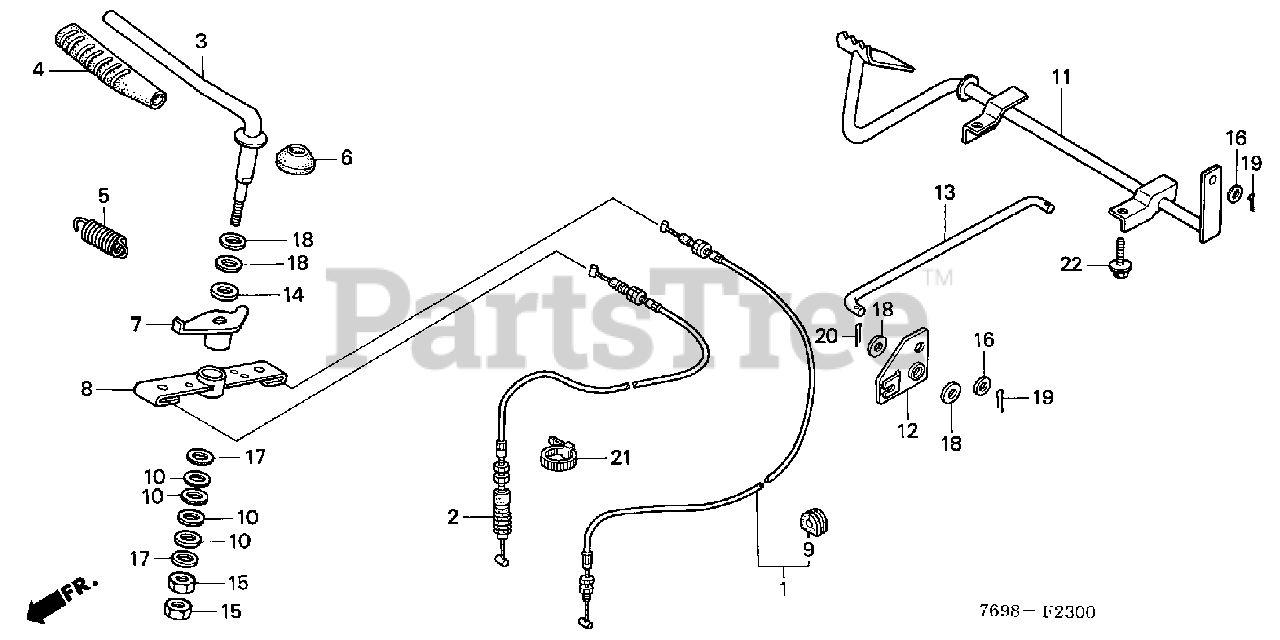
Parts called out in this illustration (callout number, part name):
1	CABLE, ACCELERATOR
2	CABLE, FOOT ACCELERATOR
3	LEVER, THROTTLE
4	GRIP, THROTTLE LEVER *YR161* (ORANGE)
5	SPRING, THROTTLE RETURN
6	COVER, THROTTLE LEVER
7	PLATE, THROTTLE CONTROL
8	HOLDER, THROTTLE CABLE
9	GROMMET, WIRE
10	WASHER, CONICAL SPRING
11	PEDAL, ACCELERATOR
12	ARM, ACCELERATOR PEDAL
13	ROD, ACCELERATOR PEDAL
14	WASHER, THRUST (12MM)
15	NUT, HEX. (8MM)
16	WASHER, PLAIN (6MM)
17	WASHER, PLAIN (8MM)
18	WASHER, FLAT (12MM)
19	PIN, COTTER (2.0X15)
20	PIN, COTTER (2.0X22)
20	PIN, COTTER (2.0X35)
21	BAND B1, CABLE
22	BOLT, FLANGE (6X10)
